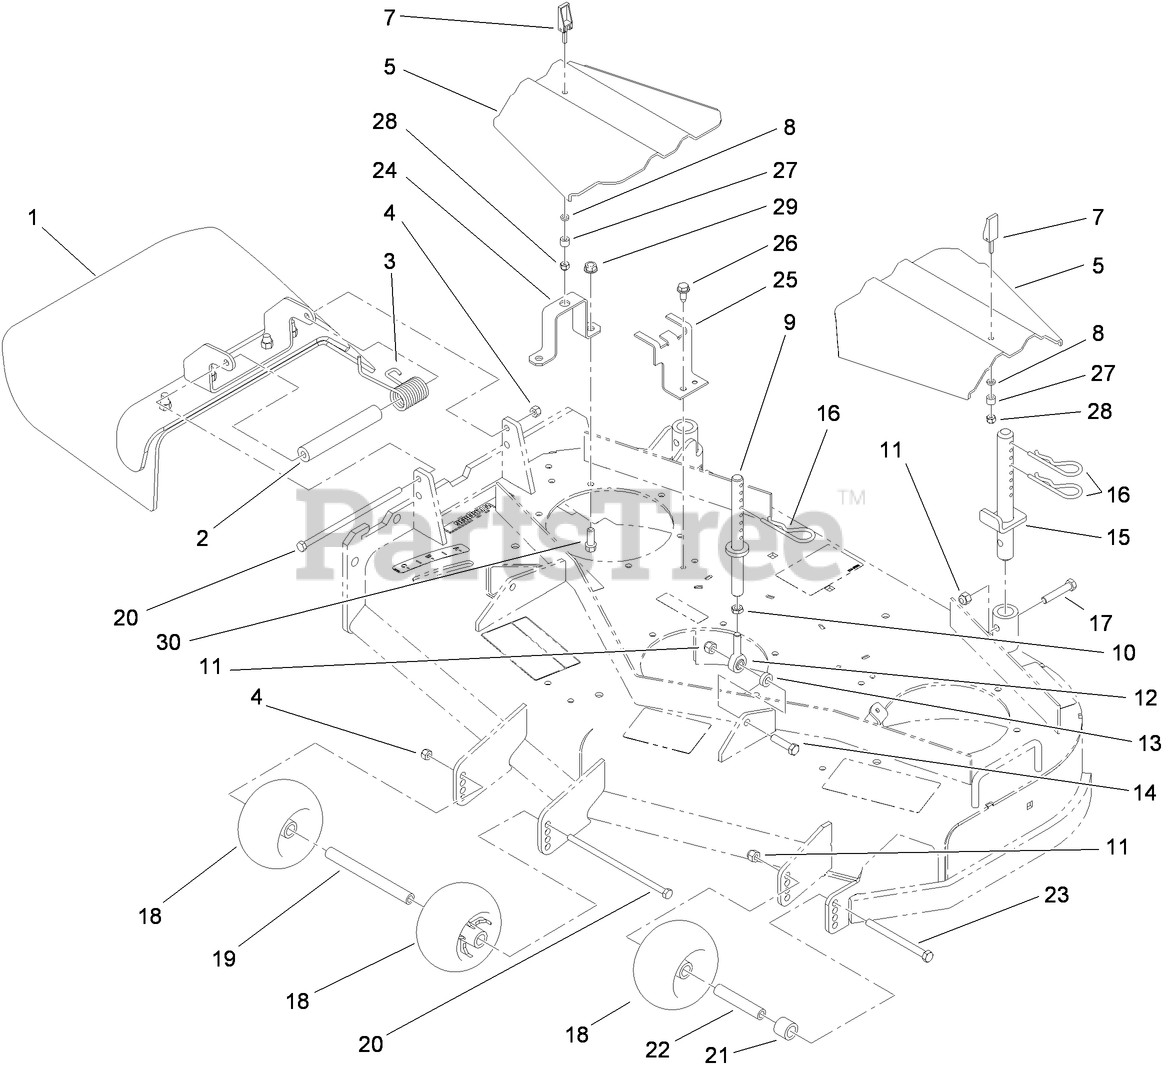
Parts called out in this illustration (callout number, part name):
1	DEFLECTOR ASM
2	SPACER
3	SPRING-TORSION
4	NUT-LOCK, NI
5	COVER-BELT
7	HANDLE-LATCH, SWELL
8	WASHER
9	FRONT PIN ASM
10	NUT-HJ
11	NUT-LOCK, NI
12	BALLJOINT
13	SPACER
14	SCREW-HH
15	REAR PIN ASM
16	PIN-HAIR
17	SCREW-HH
18	ROLLER-SCALP, ANTI
19	SPACER-WHEEL
20	SCREW-HH
21	TUBE-SPACER
22	TUBE-SPANNER
23	SCREW-HH
24	BRACKET-COVER
25	BRACKET-COVER
26	SCREW-HWHTF
27	BUSHING-LATCH, SWELL
28	NUT-LOCK, HH
29	NUT-HHF, WHIZ
30	SCREW-HWH
